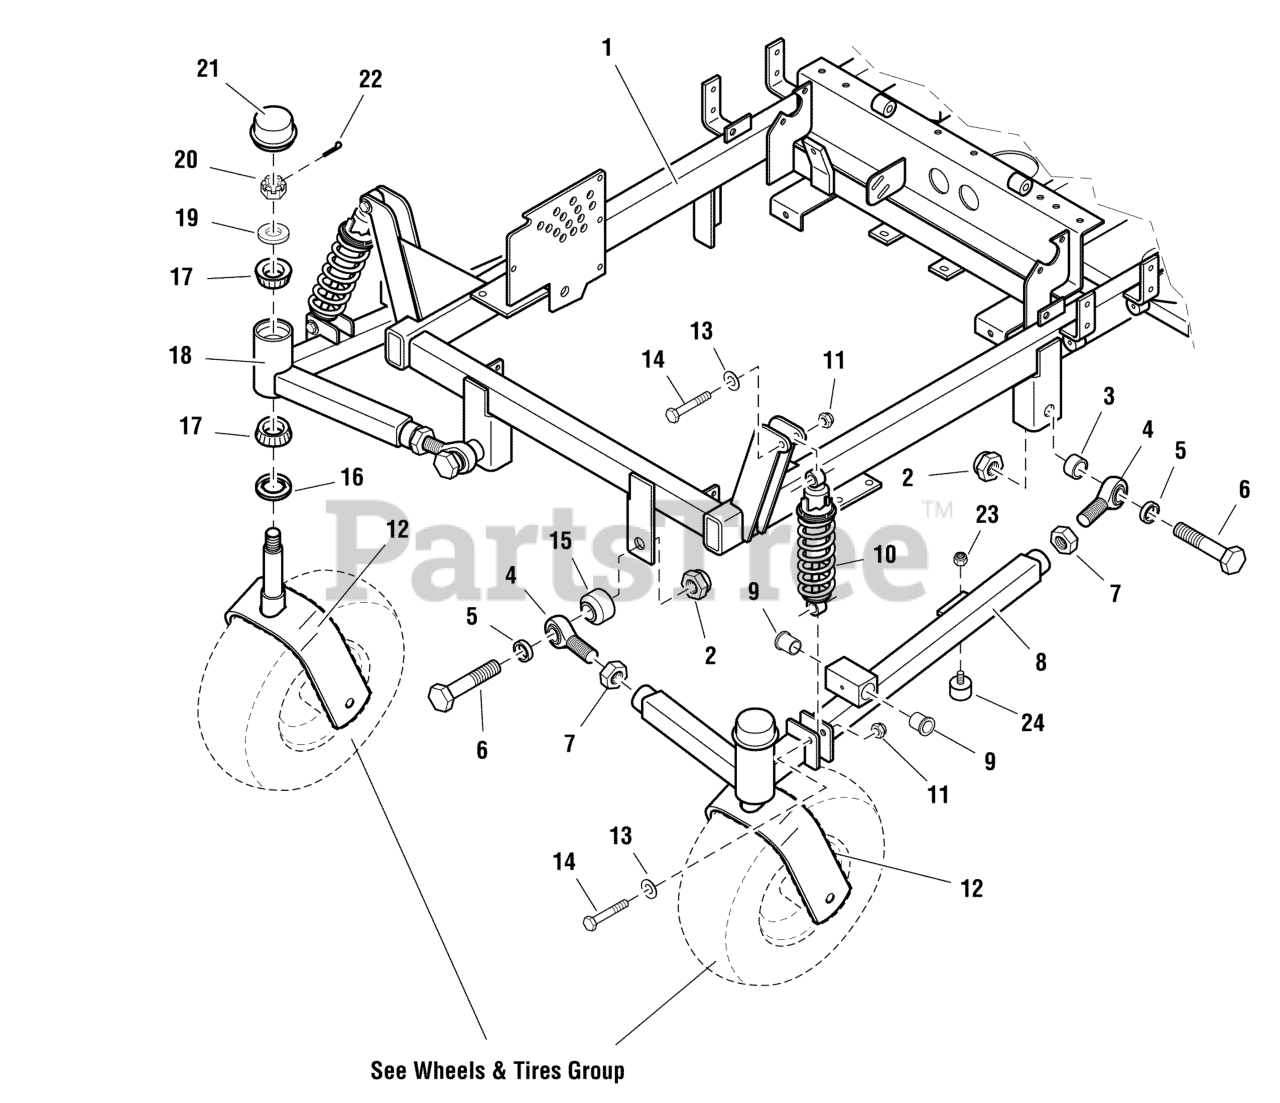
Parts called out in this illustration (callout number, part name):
1	MAIN FRAME
2	NUT, 3/4-16 Hex Nylon Lock
3	SPACER, .76 x 1.00 x .50
4	BALL JOINT, 3/4-16 Male
5	SPACER, .76 x 1.00 x .25
6	BOLT, 3/4-16 x 3-1/2
7	NUT, 3/4-16 Hex Jam
8	ASSM, A-ARM, LH
9	BUSHING, Flange
10	SHOCK & SPRING ASSEMBLY
11	NUT, 3/8-16 HEX NYLON LOCK
12	CASTER TIRE MOUNT
13	WASHER, 3/8 SAE
14	BOLT, 3/8-16 X 2-1/4" GD5 CZ
15	SPACER, .75 x 1.50 x 1.00
16	SEAL, GREASE
17	BEARING, Tapered Roller
18	SUSPENSION ARM ASSEMBLY - RH
19	WASHER, 3/4 SAE
20	NUT, 3/4-16 Hex Slotted
21	CAP
22	PIN, COTTER, 1/8 X 1-1/4
23	NUT, 1/4-20 HEX NYLON LOCK
24	RUBBER BUMPER
